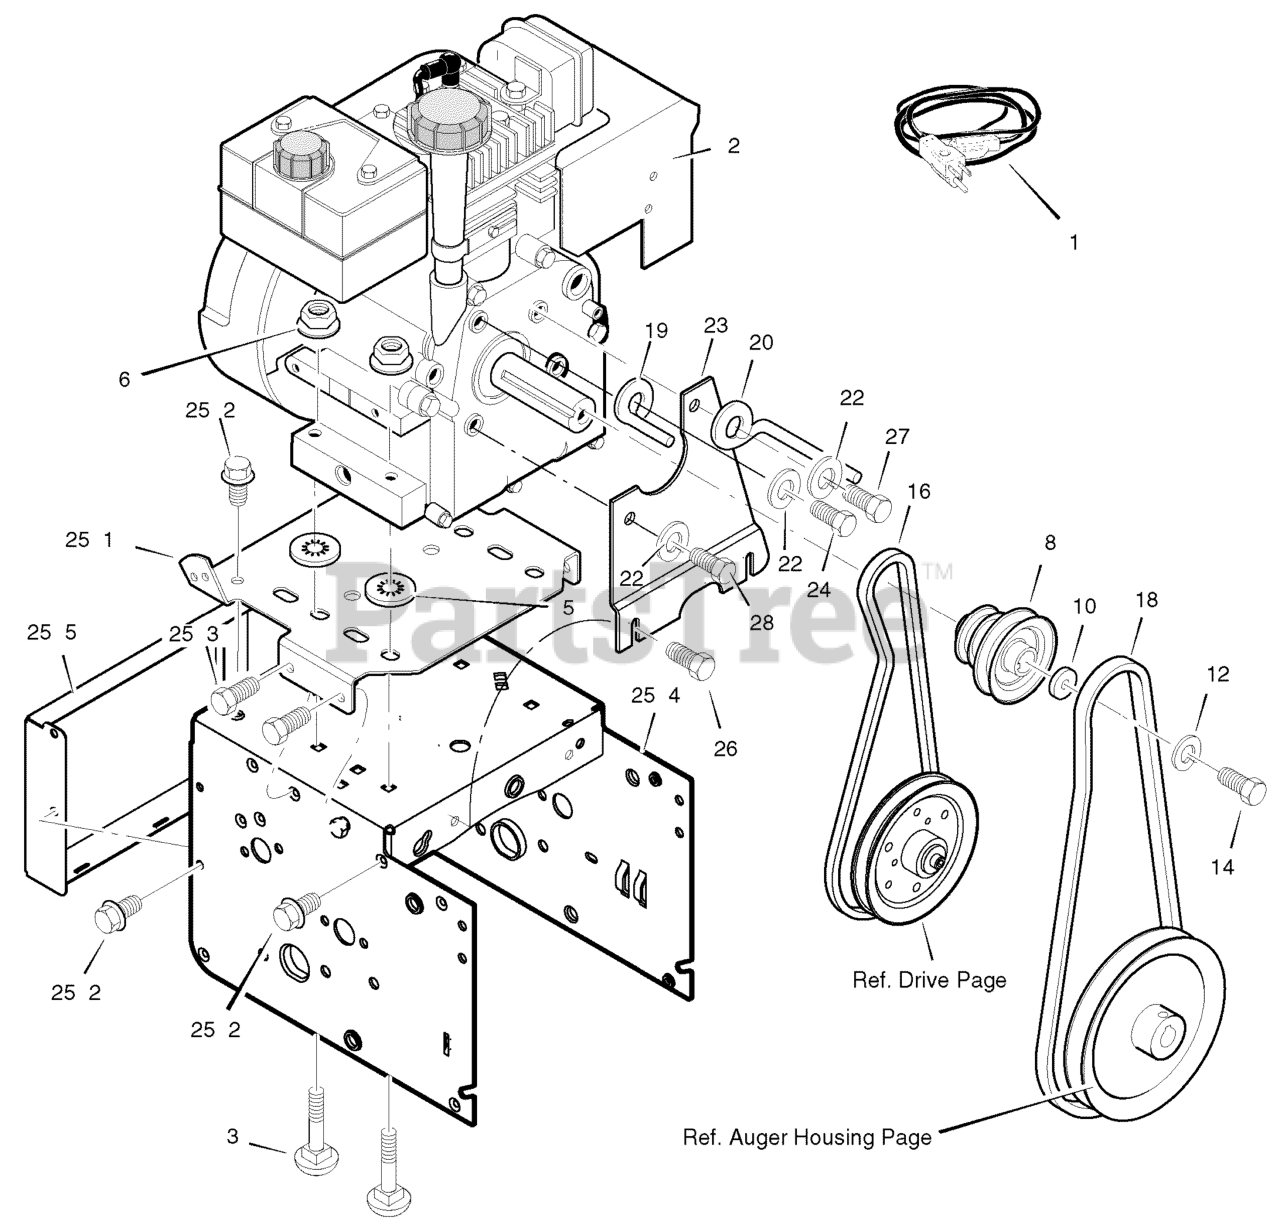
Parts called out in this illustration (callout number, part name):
1	CORD, STARTER
2	ENGINE
3	BOLT, CARRIAGE 5/16-18
5	RETAINER, PUSH
6	NUT, HEX 5/16-18
8	PULLEY, ENGINE
10	WASHER
12	WASHER
14	SCREW, 3/8-24 x 1.00
16	BELT, HYDRO DRIVE
18	BELT, AUGER V 4L
19	GUIDE, BELT
20	GUIDE, BELT
22	WASHER, .31X.58X.08
23	PLATE, VIBRATION
24	SCREW, 5/16-24 x 0.75
25	FRAME ASSEMBLY
26	SCREW
27	BOLT, HEX 5/16-24 X 1.00
28	BOLT, HEX 5/16-24 X 0.63
